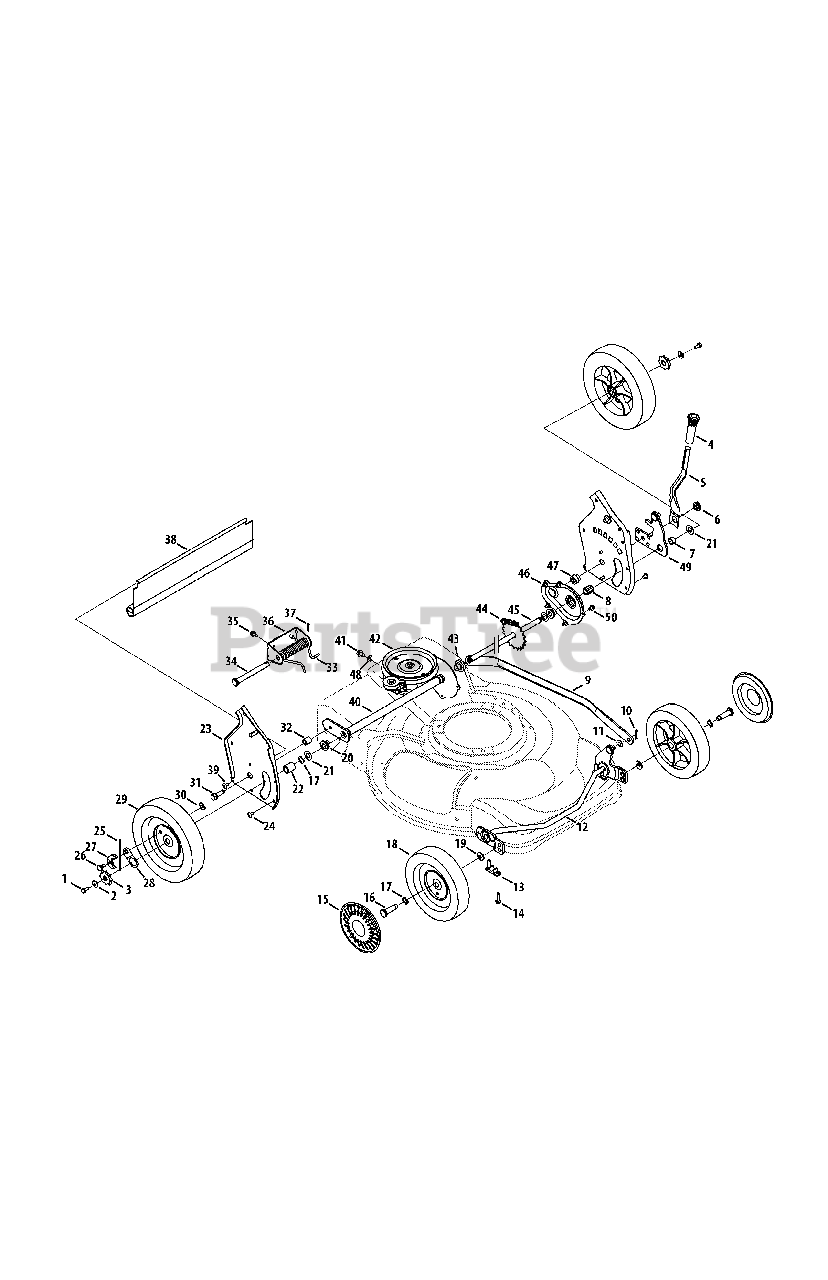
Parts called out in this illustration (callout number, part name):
1	HH Cap Screw 1/4-20 x .620
2	Bell Washer .265 x .75 x .062
3	Wheel Ratchet
5	Spring Lever
6	Shoulder Nut
7	Spacer .51 x .70 x .38
8	Hex Sleeve Bearing
9	Single Lever Control Arm
10	Hairpin Clip
11	Spring Washer
12	Front Axle Assembly
13	Block Bushing
14	Hex Screw 1/4-15 x 1
15	Hubcap
16	Shoulder Scr., .498x1.445x3/8-16
17	Wave Washer .510 x .750 x .017
18	Front Wheel
19	Bell Washer .375 x .870 x .063
20	Hex Flange Bearing
21	Flat Washer .508 x 1 x .020
22	Spacer .550 x .755 x 1.1
23	Handle Bracket Assy RH
23	Handle Bracket Assy LH
24	AB Screw 1/4-14 x .50
25	Plastic Ratchet Spring
26	Shoulder Scr., .340x.285x1/4-20
27	Pawl - RH
27	Pawl - LH
28	Ratchet Pawl Plate
29	Rear Wheel
30	Weld Nut
31	TT Screw 3/8-16 x 1.25
32	Spacer .385 x .625 x .700
33	Torsion Spring RH
34	Clevis Pin .500 x 4.62
35	TT Screw 1/4-20 x .625
36	Lift Assist Spring Bracket
37	Cotter Pin
38	Trail shield
39	AB Screw, #10-16 x .500
40	Transmission Axle Assembly
41	TT Screw 5/16-18 x .625
42	Transmission
43	Hex Flange Bearing
44	Chain
45	Axle Assembly RR
46	Chain Cover Assembly
47	Shoulder Spacer .385 x .715
48	Flat Washer, .349 x .879 x .063
49	RR Pivot Arm Assembly
50	TT Screw, 1/4-20 x .375
